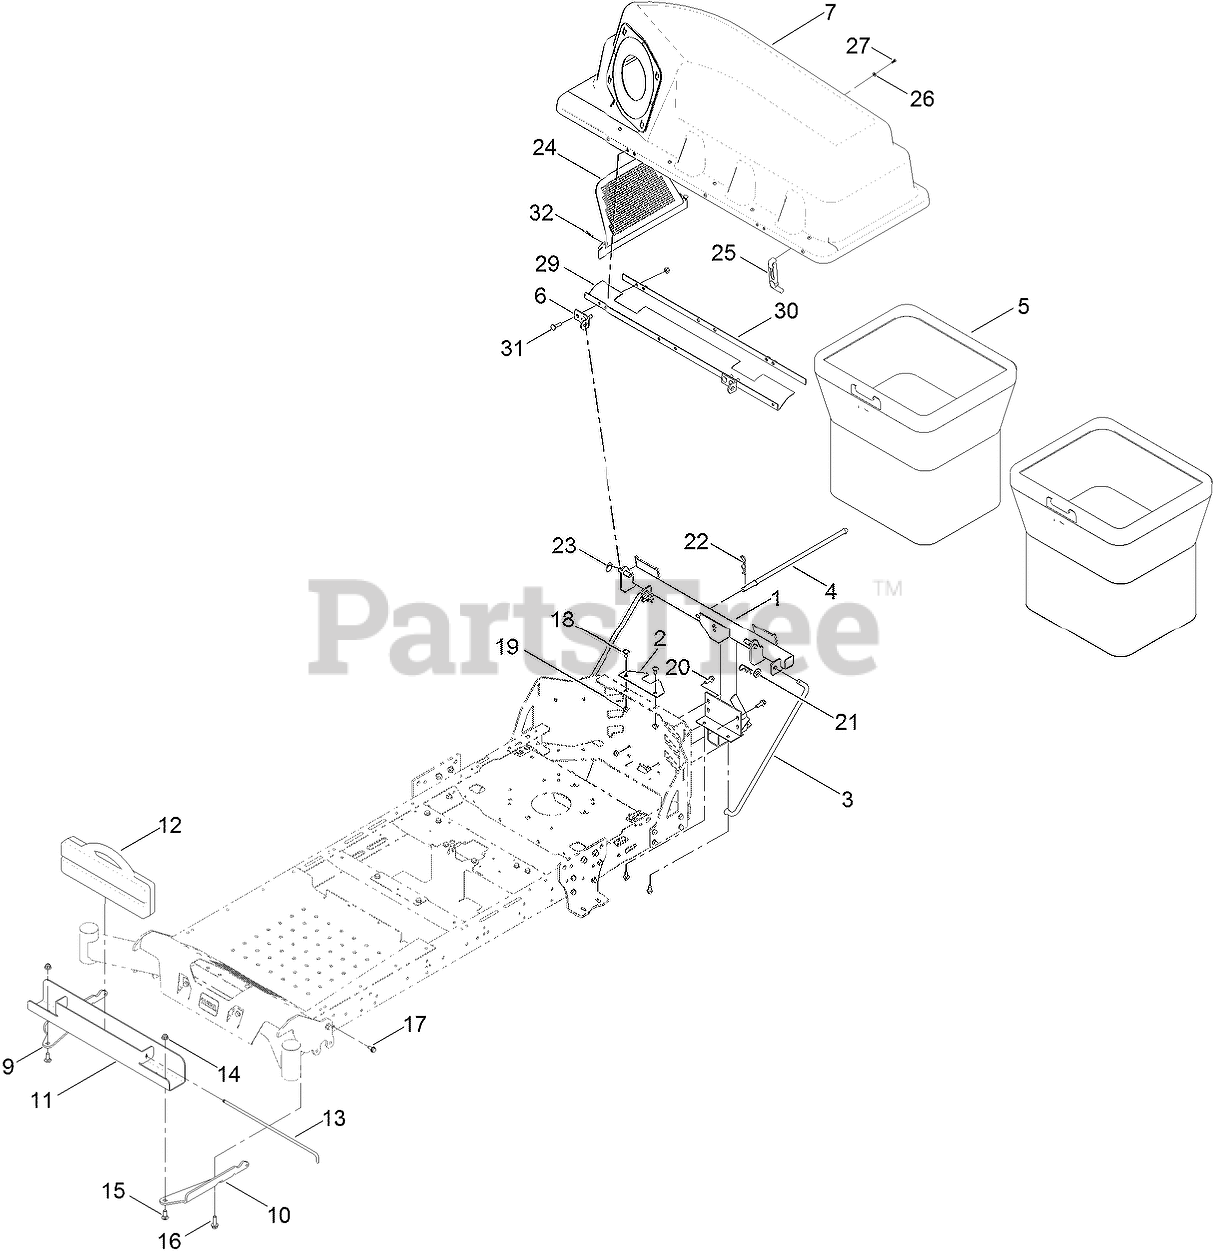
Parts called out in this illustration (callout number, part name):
1	FRAME-PIVOT
2	BRACKET-STABILIZER
3	ROD-SUPPORT
4	ROD-HOOD, DOWN (HOLD)
5	BAG ASM
6	BRACKET-PIVOT, HOPPER
7	BAGGER HOOD ASM
9	BRACKET-WEIGHT, RH
10	BRACKET-WEIGHT, LH
11	CHANNEL-WEIGHT, BAGGER
12	WEIGHT-35 POUND
13	PIN-WEIGHT
14	NUT-HF, NI
15	BOLT-CARR
16	SCREW-HHF
17	SCREW-HWHTF
18	BOLT-CARR
19	NUT-HF, NI
20	SCREW-HHF
21	WASHER-FLAT
22	PIN-HAIR
23	PIN-COTTER, CIRCULAR
24	SCREEN-BAGGER
25	LATCH-RUBBER
26	WASHER-FLAT
27	SCREW-PLASTITE
30	PLATE-BACKING
31	SCREW-CARR
32	PIN-COTTER
